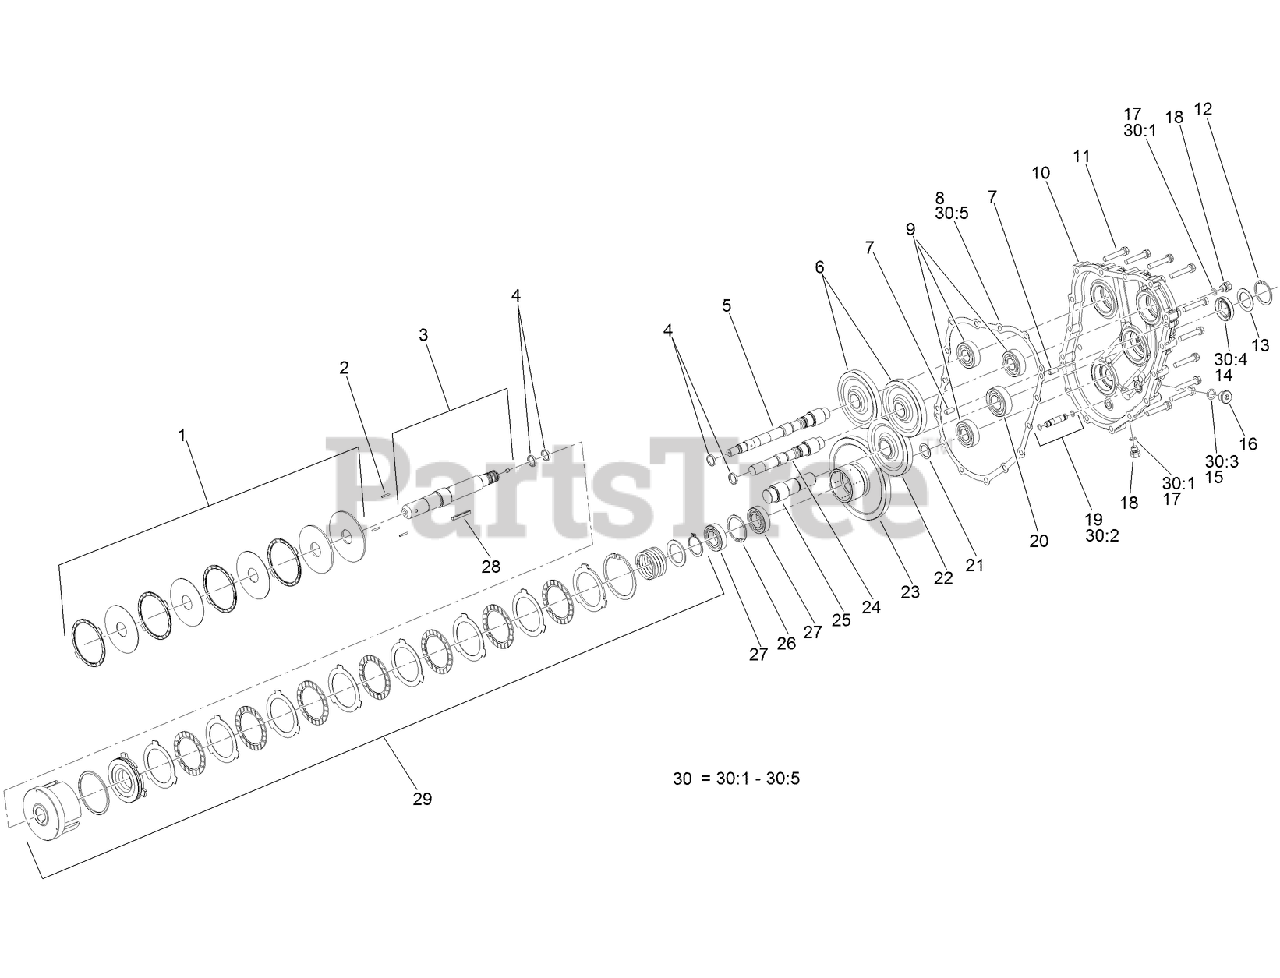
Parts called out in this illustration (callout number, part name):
1	PTO BRAKE ASM
2	ROD-PUSH
3	PTO SHAFT ASM
4	RING-SEAL
5	SHAFT-PUMP
6	GEAR-PUMP
7	PIN-PARALLEL
8	GASKET-HOUSING, GEAR
9	BEARING
10	HOUSING-CASE, GEAR
12	RING-SNAP
13	SPACER
16	PLUG-NPTF
17	O RING-PLUG
20	BEARING
21	SPACER
22	GEAR-INPUT
23	GEAR-PTO
24	SHAFT-PUMP
25	SHAFT-INPUT
26	RING-SNAP
27	BEARING
29	CLUTCH CYLINDER ASM
30	GEAR HOUSING SEAL KIT
30:1	O RING-PLUG
30:2	Deck ASM
30:5	GASKET-HOUSING, GEAR
